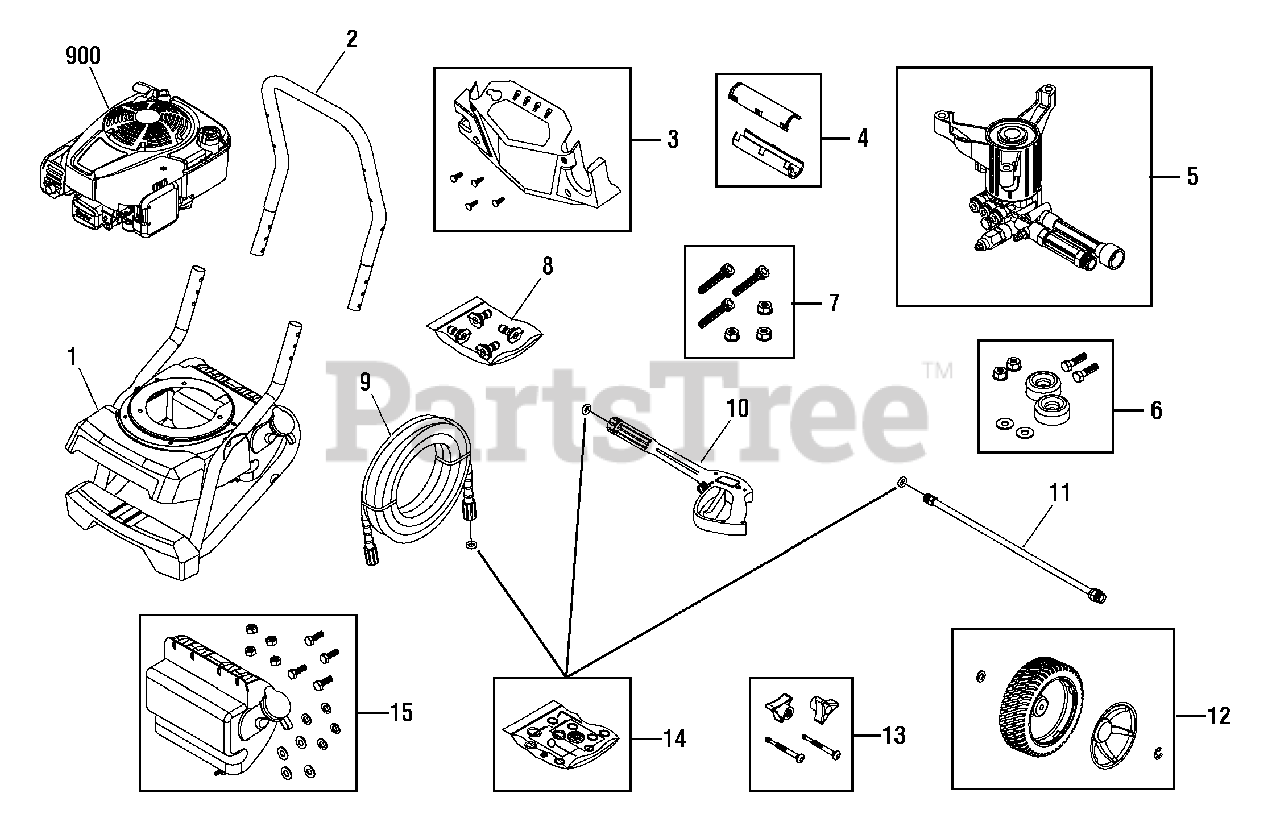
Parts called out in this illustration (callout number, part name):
6	MOUNT, Vibration
7	KIT, Hardware, Pump Mounting
8	KIT, QC Nozzles
9	HOSE
10	GUN
11	EXTENSION, QC
13	KIT, Hardware, Handle
14	KIT, O-Rings
15	TANK, Chemical
900	* ENGINE
